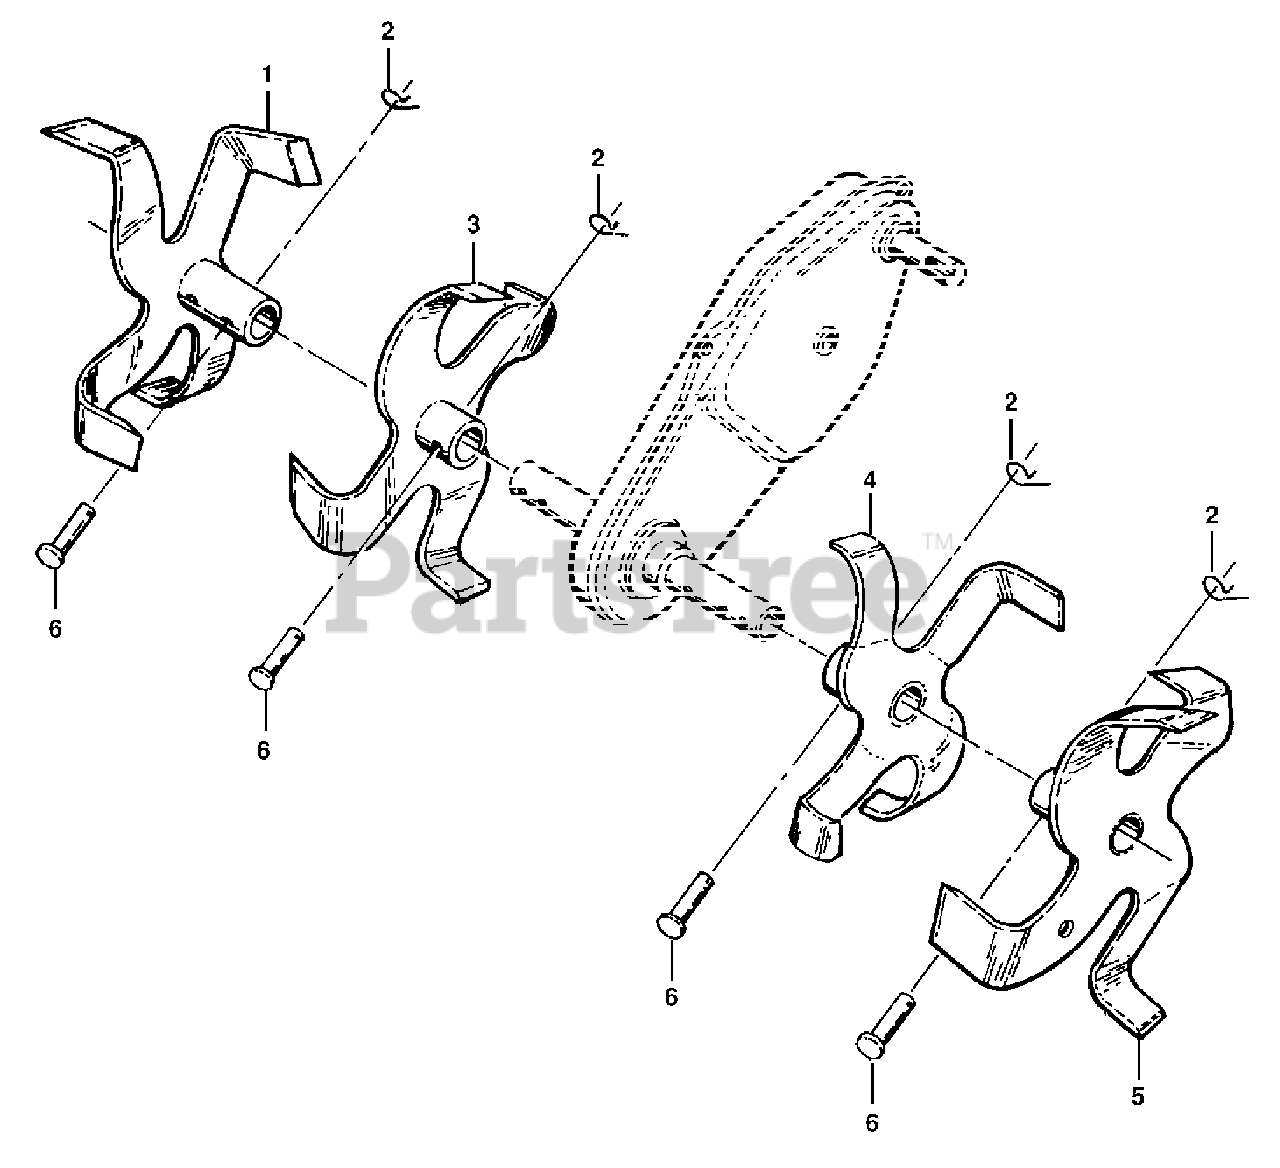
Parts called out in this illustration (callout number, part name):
1	Tine, Outer, R.H.
2	Retainer, Spring
3	Tine, Inner, R.H.
4	Tine, Inner, L.H.
5	Tine, Outer, L.H.
6	Pin, Clevis
